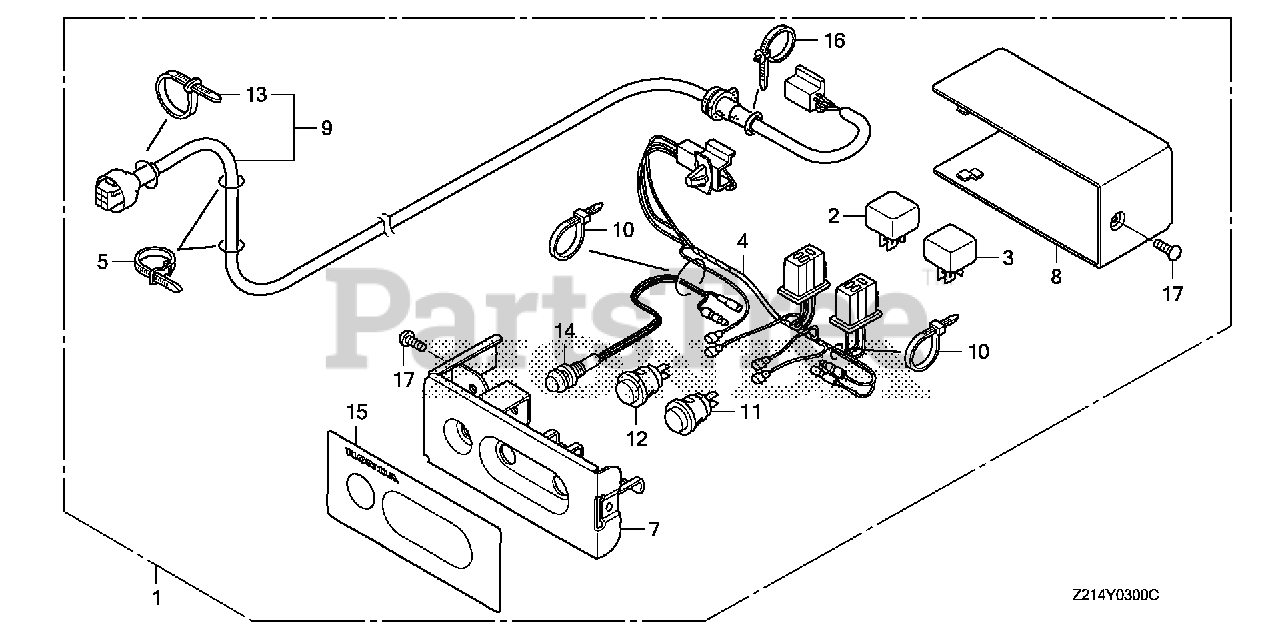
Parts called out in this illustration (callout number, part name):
1	CONTROL KIT, REMOTE (10M) *NH105* (MAT BLACK)
1	CONTROL KIT, REMOTE (20M) *NH105* (MAT BLACK)
1	CONTROL KIT, REMOTE (30M) *NH105* (MAT BLACK)
2	RECTIFIER, SILICON
3	RECTIFIER, SILICON
4	HARNESS ASSY., REMOTE CONTROL
5	BAND, WIRE Use up to Frame SN 1001879.
7	PANEL, REMOTE CONTROL *NH105* (MAT BLACK)
8	COVER, REMOTE CONTROL *NH105* (MAT BLACK)
9	CABLE ASSY., REMOTE CONTROL (10M)
9	CABLE ASSY., REMOTE CONTROL (20M)
9	CABLE ASSY., REMOTE CONTROL (30M)
10	TIE, CABLE (C)
11	SWITCH, ENGINE STOP
12	SWITCH, START
13	BAND (BLACK 3.5X140)
14	LED ASSY.
15	MARK, REMOTE CONTROL
16	BAND, HARNESS (98MM) (NATURAL)
17	SCREW, PAN (4X8)
